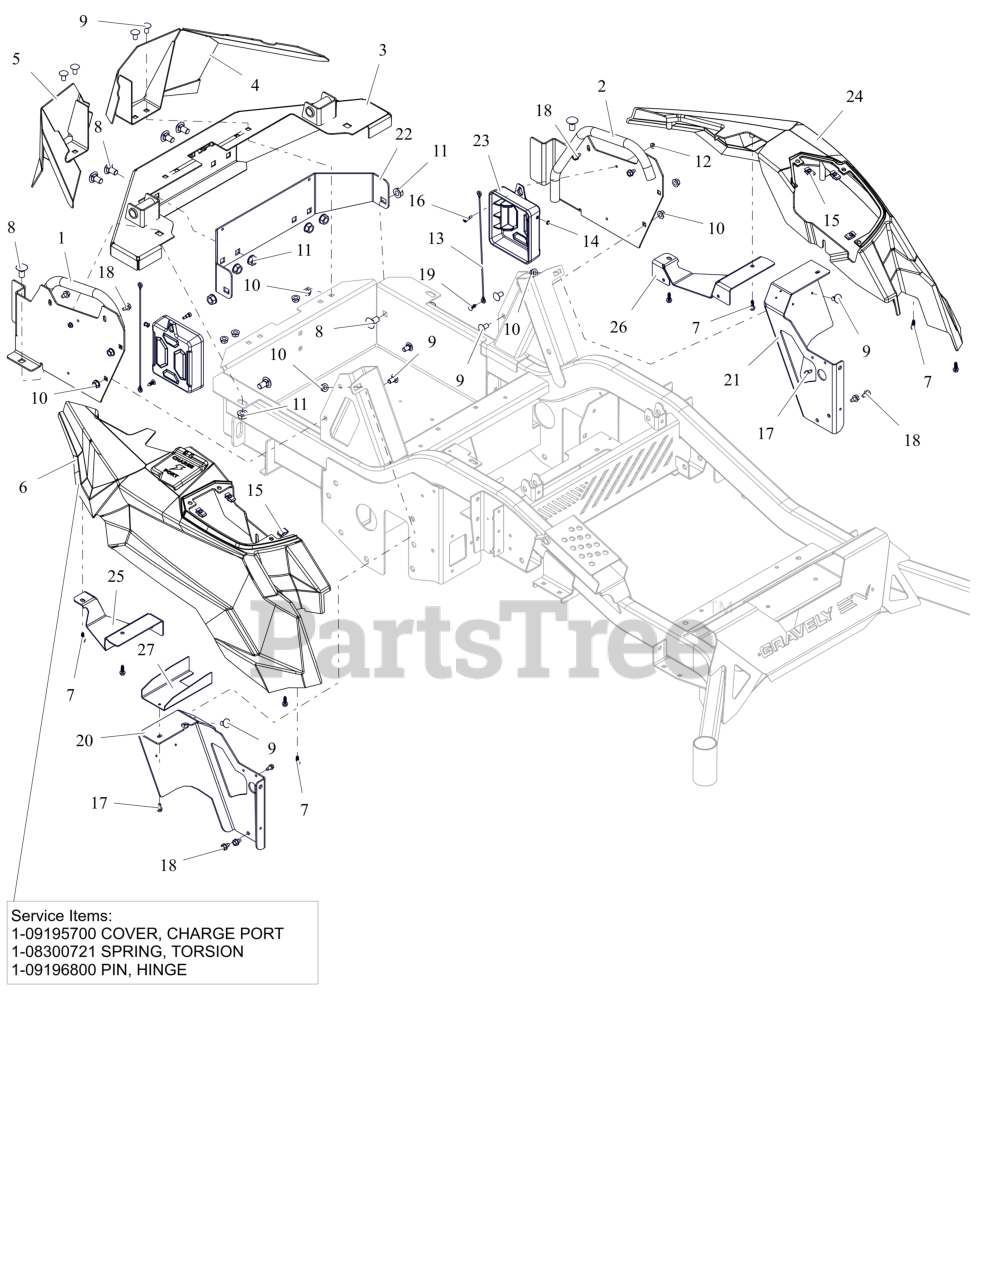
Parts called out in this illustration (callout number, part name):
1	WLDMT, REAR FENDER MOUNT-RH (RED)
2	WLDMT, REAR FENDER MOUNT-LH (RED)
3	WLDMT, BUMPER PT EV (RED)
4	WLDMT, REAR WRAP-LH (BLACK)
5	WLDMT, REAR WRAP-RH (BLACK)
6	ASM, FENDER RH PRO-TURN EV
6	COVER, CHARGE PORT
6	SPRING, TORSION
6	PIN, HINGE
7	SCR, PLASTITE-HWH 0.25 X 0.75 ZC120
8	BLT, RHSN .50-13X1.00 G5 ZCC
9	BTL,RHSSN .375-16 X 0.75 G5 FPB
10	NUT-LK-CTR-FLG .375-16 GF ZCC
11	NUT-LK-CTR-FLG .500-13 GG ZCC
12	NUT, FLG-TOP LK #10-24 GRF ZCC
13	CABLE, 12.0 LANYARD, NYLON
14	POST, & SCREW, PUSH LOCK .25 X .25
15	NUT-RTNR .25-20X.56
16	BLT-SHLDR .25X.375
17	SCR-TAP .25-20X.50 HWH ZCC
18	SCR,TAP .312-18X.50 HWH TR ZCC
19	RIVET, .25 NYLON PANEL
20	MOUNT, FRONT FENDER-RH
21	MOUNT, FRONT FENDER-LH
22	SUPPORT, BUMPER (BLACK)
23	COVER, BATTERY BUSBAR TERMINAL
24	FENDER, LH PRO-TURN EV
25	SHIELD, FENDER MOUNT -RH (BLACK)
26	SHIELD, FENDER MOUNT-LH (BLACK)
27	SHIELD, DEBRIS -CHARGE PORT (BLACK)
